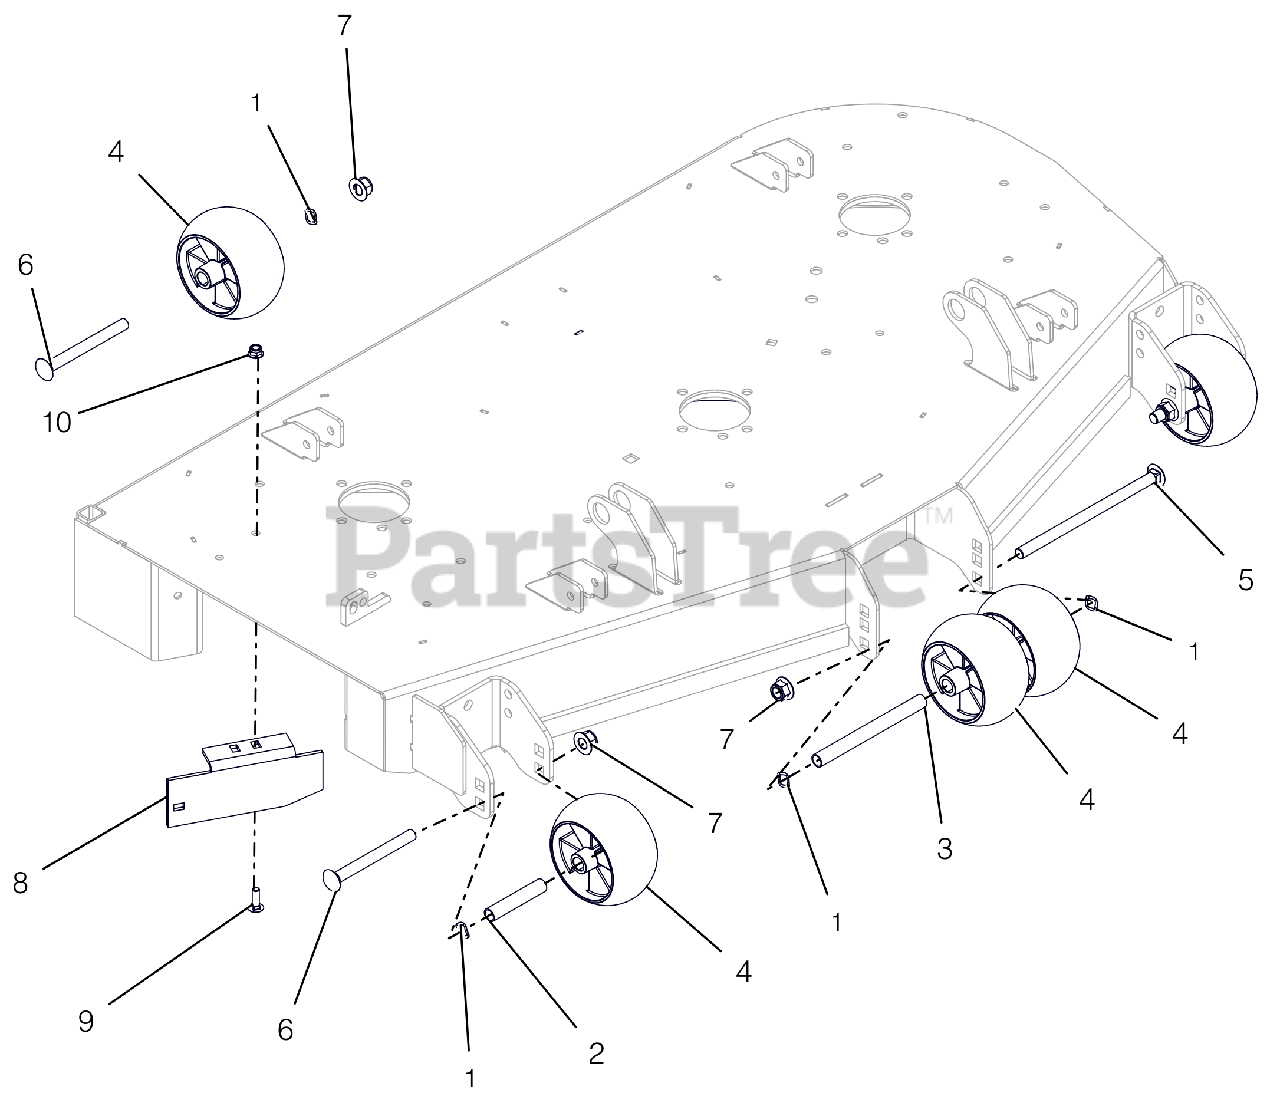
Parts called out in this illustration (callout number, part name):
1	WAVE WASHER .531X.781X.125FH
2	SPACER, .510X.625X3.35
3	SPACER, .510X.625X6.50
4	ANTI-SCALP WHEEL - 5X3 CTR
5	@BLT-RDHDSQNK .50-13X8.50 G5YZ
6	BLT-RDHDSQNK .50-13X5.00 GR5YZ
7	@NUT-LK-NYL-FLG .50-13 YWZC
8	BAFFLE, 44/48" SIDE DISCHARGE
9	@BLT-RDHDSQNK .31-18X1.00 G5YZ
10	@NUT-LK-NYL-FLG .31-18 YWZC
